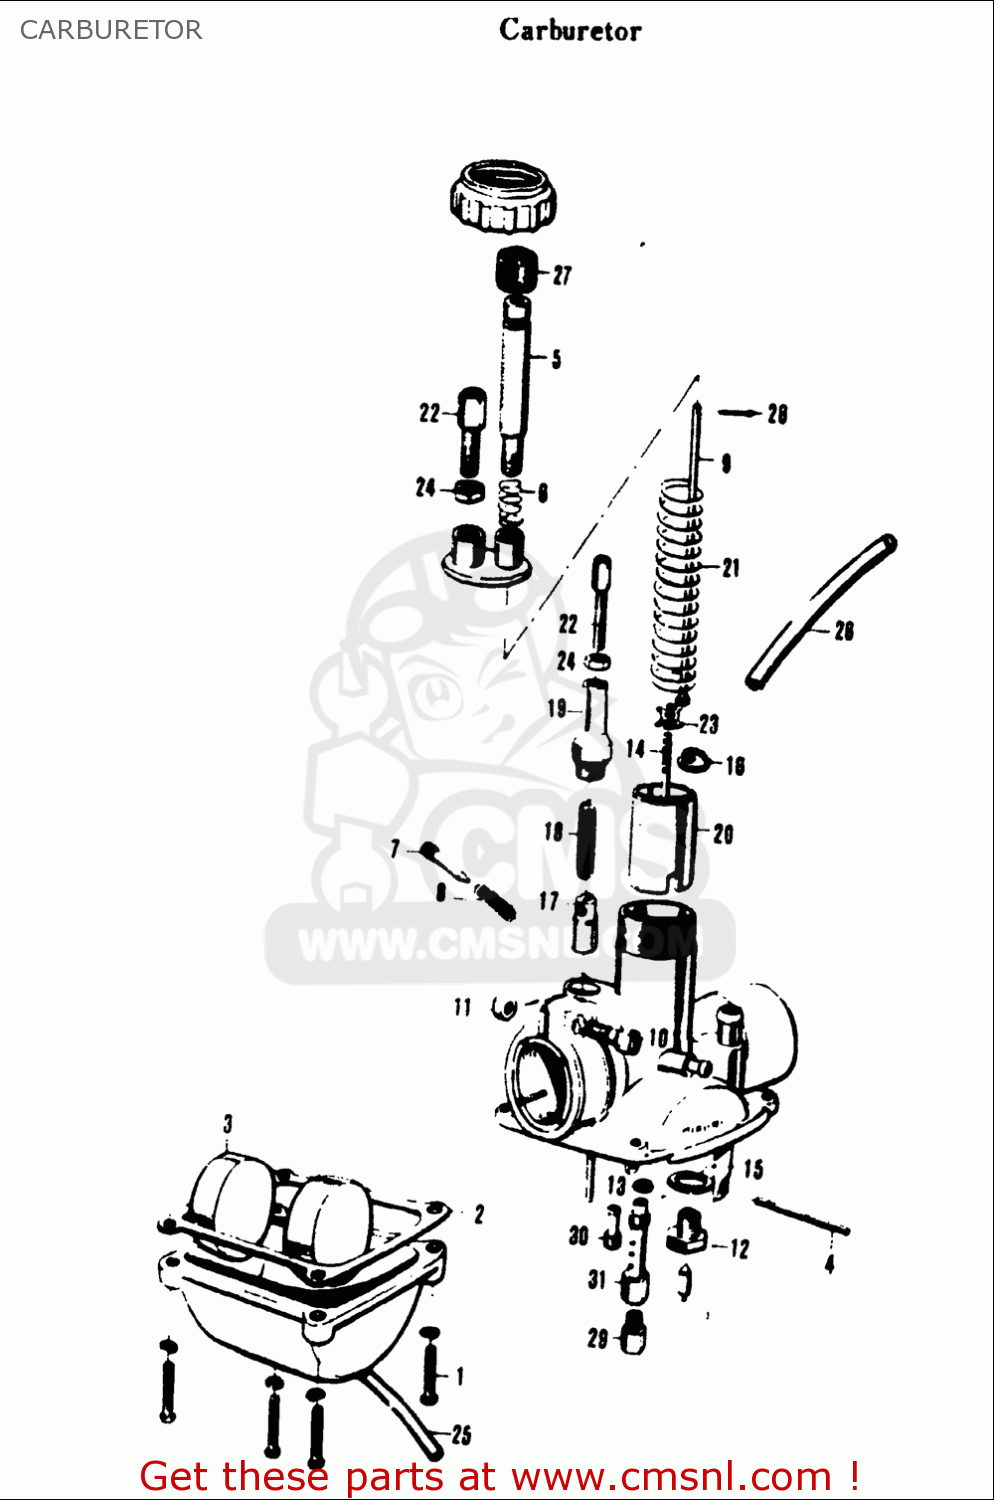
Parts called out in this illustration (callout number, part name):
2	GASKET,FLOAT CHAMBER (NAS)
3	FLOAT
4	PIN,FLOAT
5	SCREW,THROTTLE STOP
6	SPRING,THROTTLE STOP SCREW
7	SCREW,PILOT AIR
9	ROD,THROTTLE VALVE ADJUST
11	NUT
12	VALVE ASSY,NEEDLE
13	WASHER
14	NEEDLE,JET
15	GASKET,NEEDLE VALVE (NAS)
16	CLIP,NEEDLE
17	PLUNGER,STARTER
18	SPRING
19	CAP
21	SPRING,THROTTLE VALVE
22	ADJUSTER,CABLE
23	STOPPER,NEEDLE CLIP
24	NUT
27	CAP,THROTTLE VALVE STOP SCREW
29	JET,MAIN
